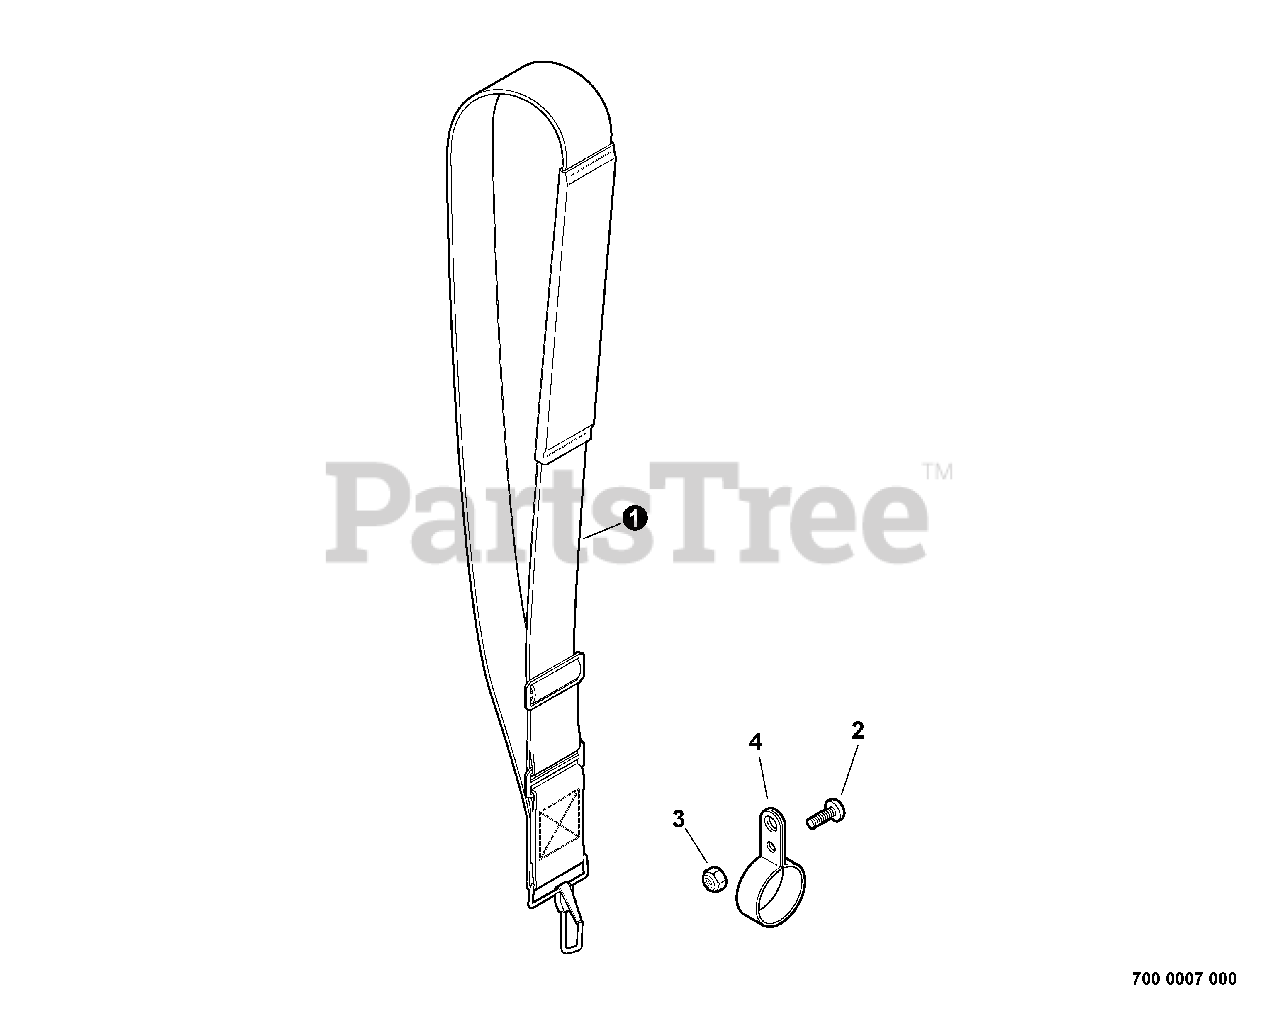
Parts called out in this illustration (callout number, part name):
1	STRAP ASSY, SHOULDER
2	SCREW 5×10
3	NUT, M5×8 NYLON INSERT
